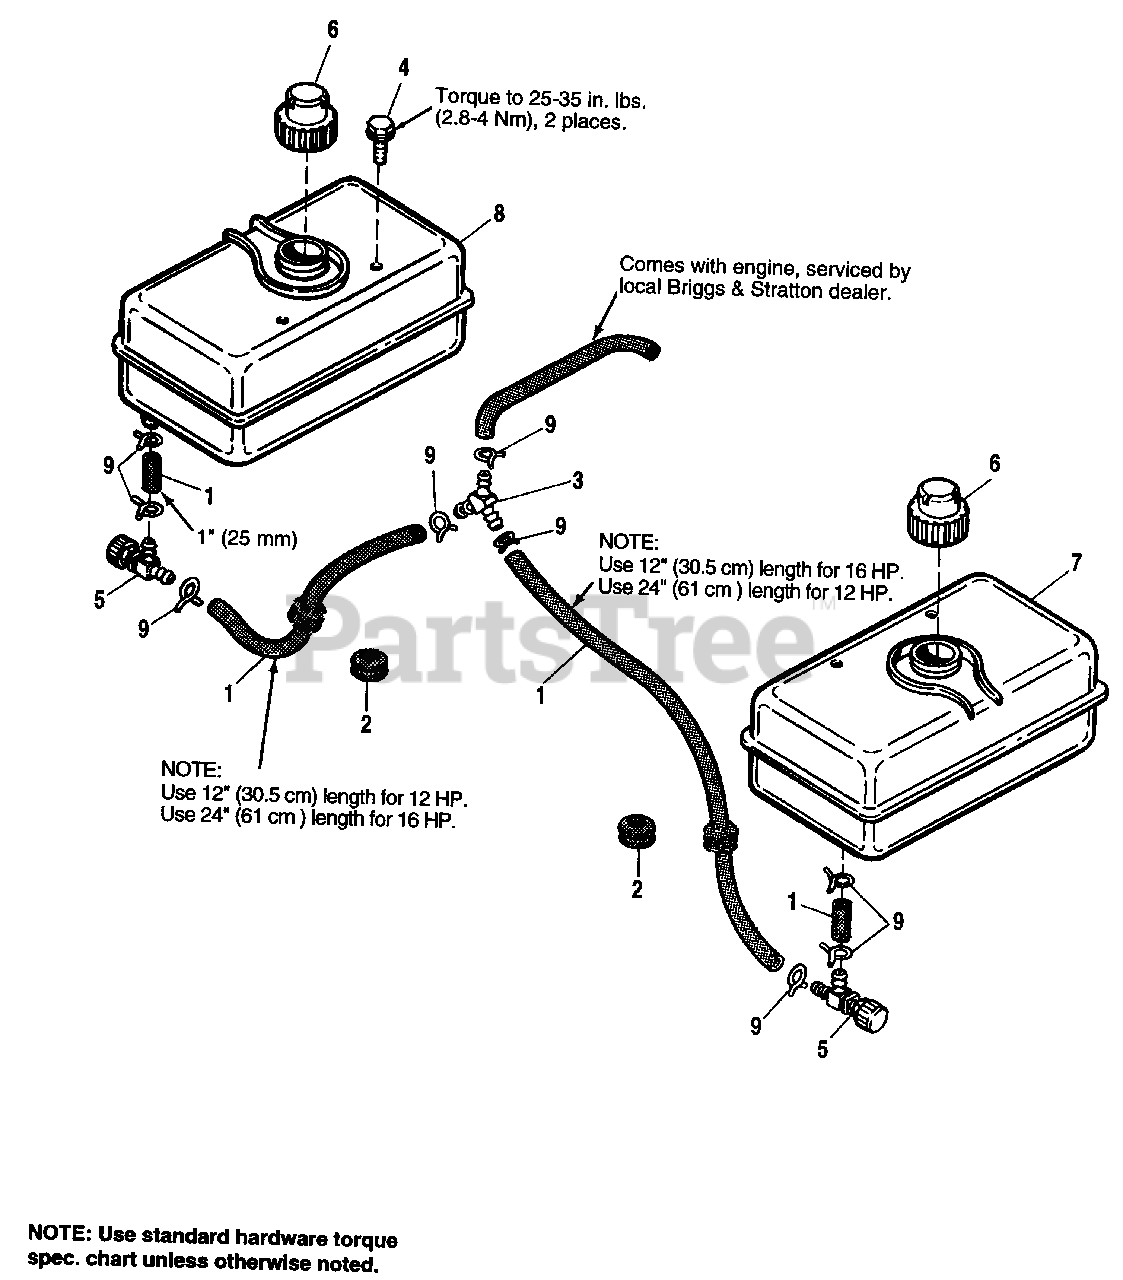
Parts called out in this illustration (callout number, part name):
1	HOSE, Fuel
3	FITTING, Tee
4	SCREW, Special
5	VALVE, Shutoff
6	CAP, Fuel Tank
7	TANK, Fuel (LH) (Incl. Qty. 1, Ref. No. 9)
8	TANK, Fuel (RH) (Incl. Qty. 1, Ref. No. 9)
9	CLAMP, Hose
